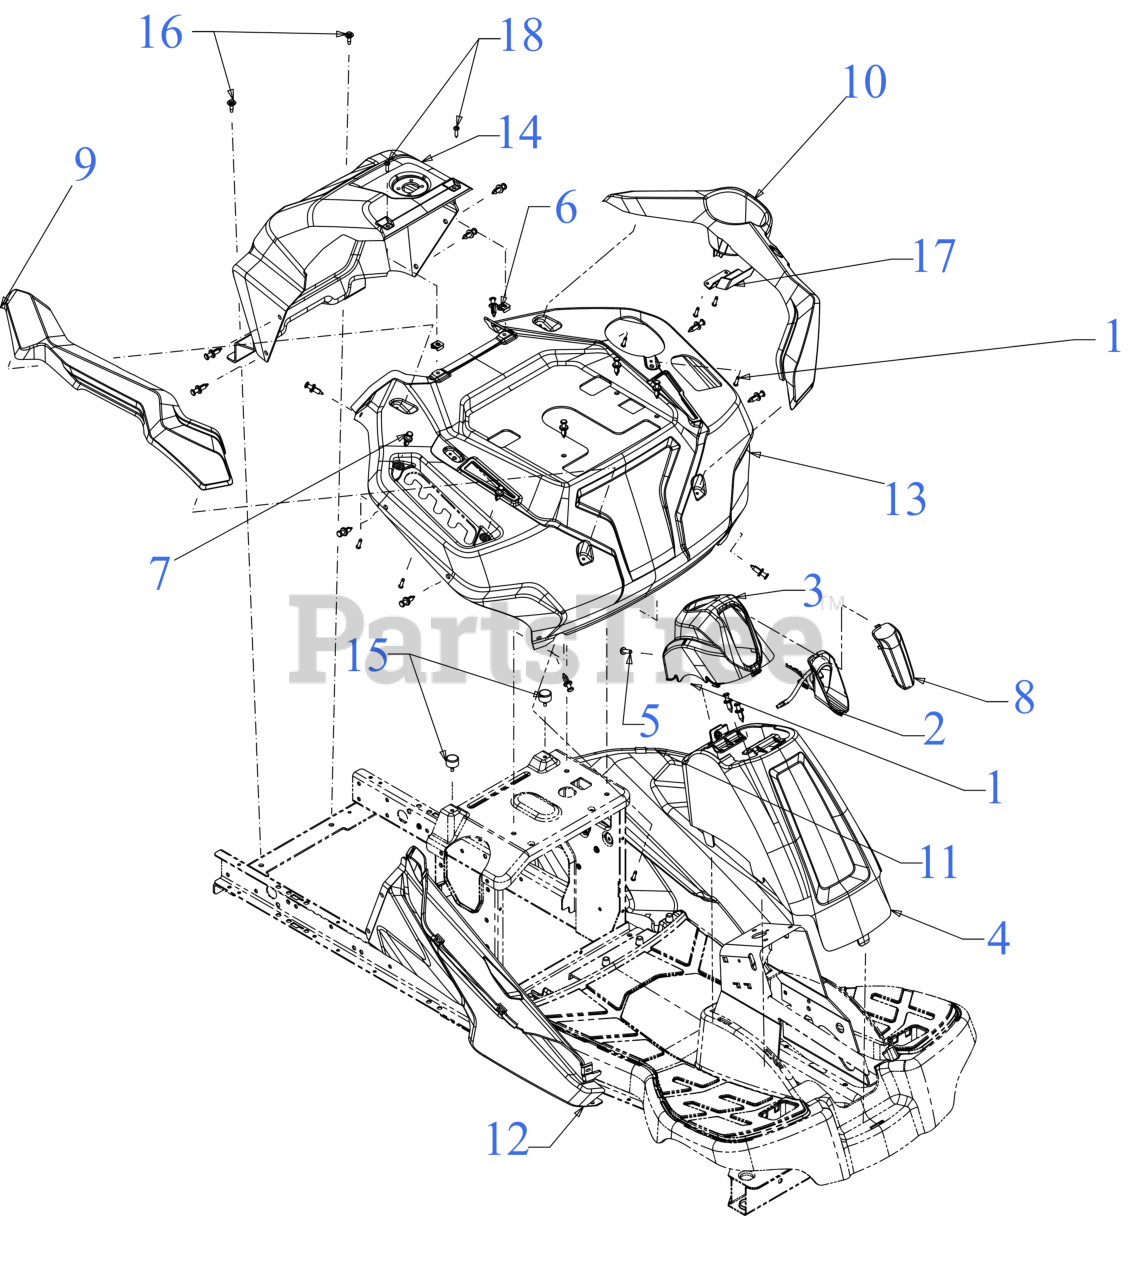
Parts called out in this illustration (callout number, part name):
1	SCREW, #8-16X.750 PH
2	LED HEADLIGHT HARNESS ASSEMBLY
3	COLUMN CAP
3	COLUMN CAP (CUB YELLOW)
4	COLUMN COVER
4	COLUMN COVER ASSEMBLY (CUB)
5	SCREW 1/4-20X.75
6	U-NUT #10-16
7	PLASTIC RIVET
8	LED HEADLIGHT LENS
9	FENDER TRIM (RH) (CUB YELLOW)
10	FENDER TRIM (LH) (CUB YELLOW)
11	BODY PANEL (LH)
12	BODY PANEL (RH)
14	BODY COVER (REAR)
15	BUMPER .62 DIA x .50
16	SHOULDER SCREW M6-1 .368 X.115
17	FENDER BRACKET
18	SCREW:10-6 x .75
